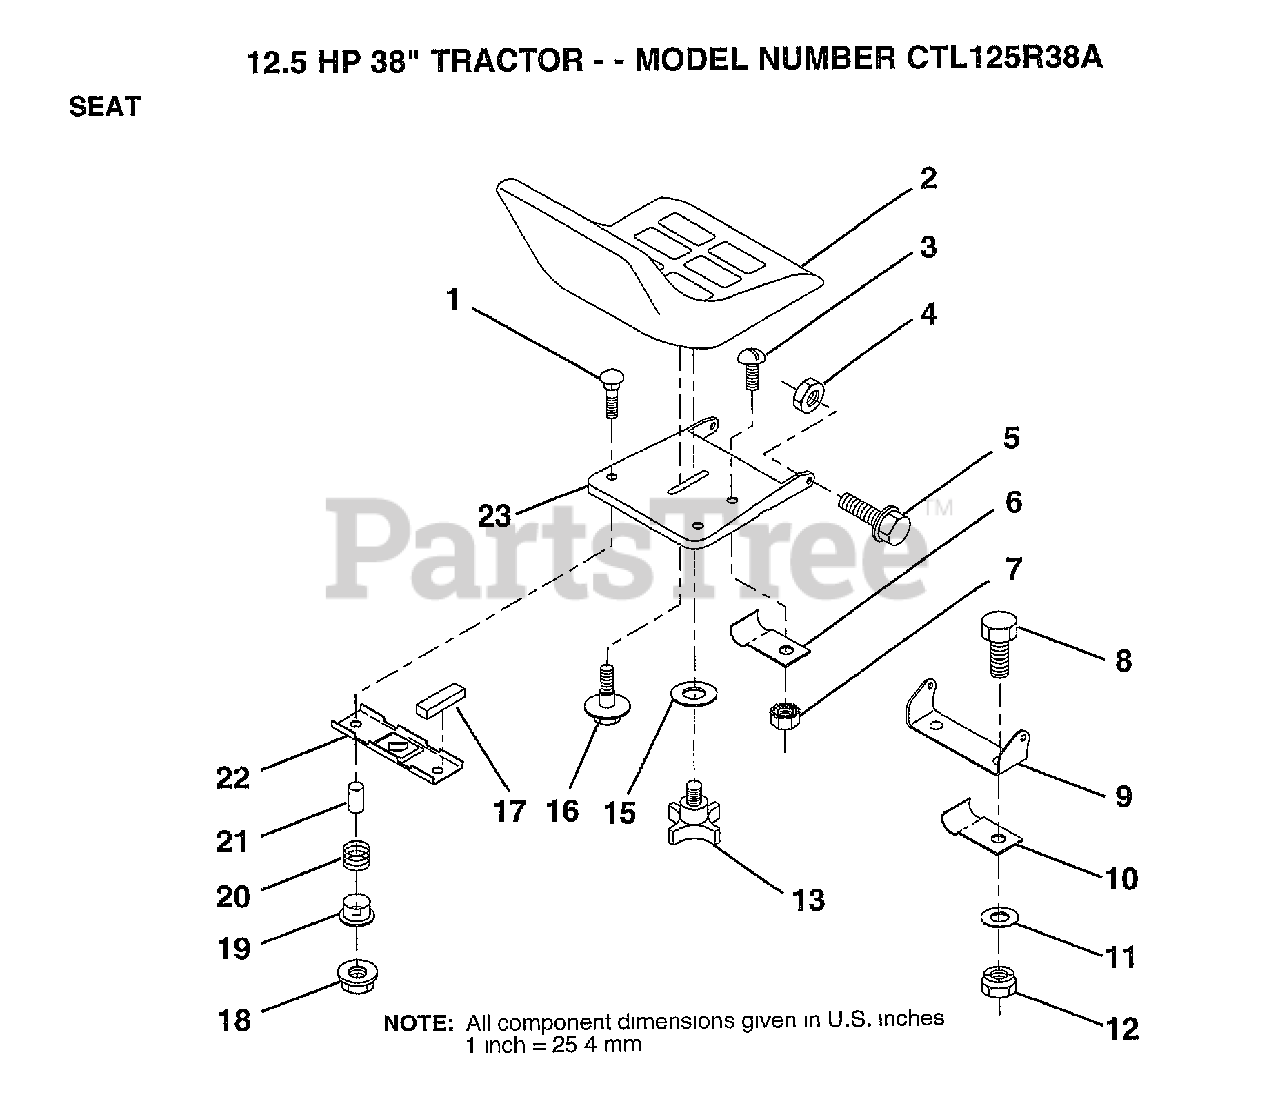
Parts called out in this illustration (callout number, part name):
7	"NUT,KEPS"
10	"CLIP,INSULATOR"
11	WASHER
15	WASHER
16	"BOLT,SHOULDER"
17	STRIP FORM
19	BUSHING
20	SPRING
21	SPLIT SPACER
22	BRKT SWITCH
